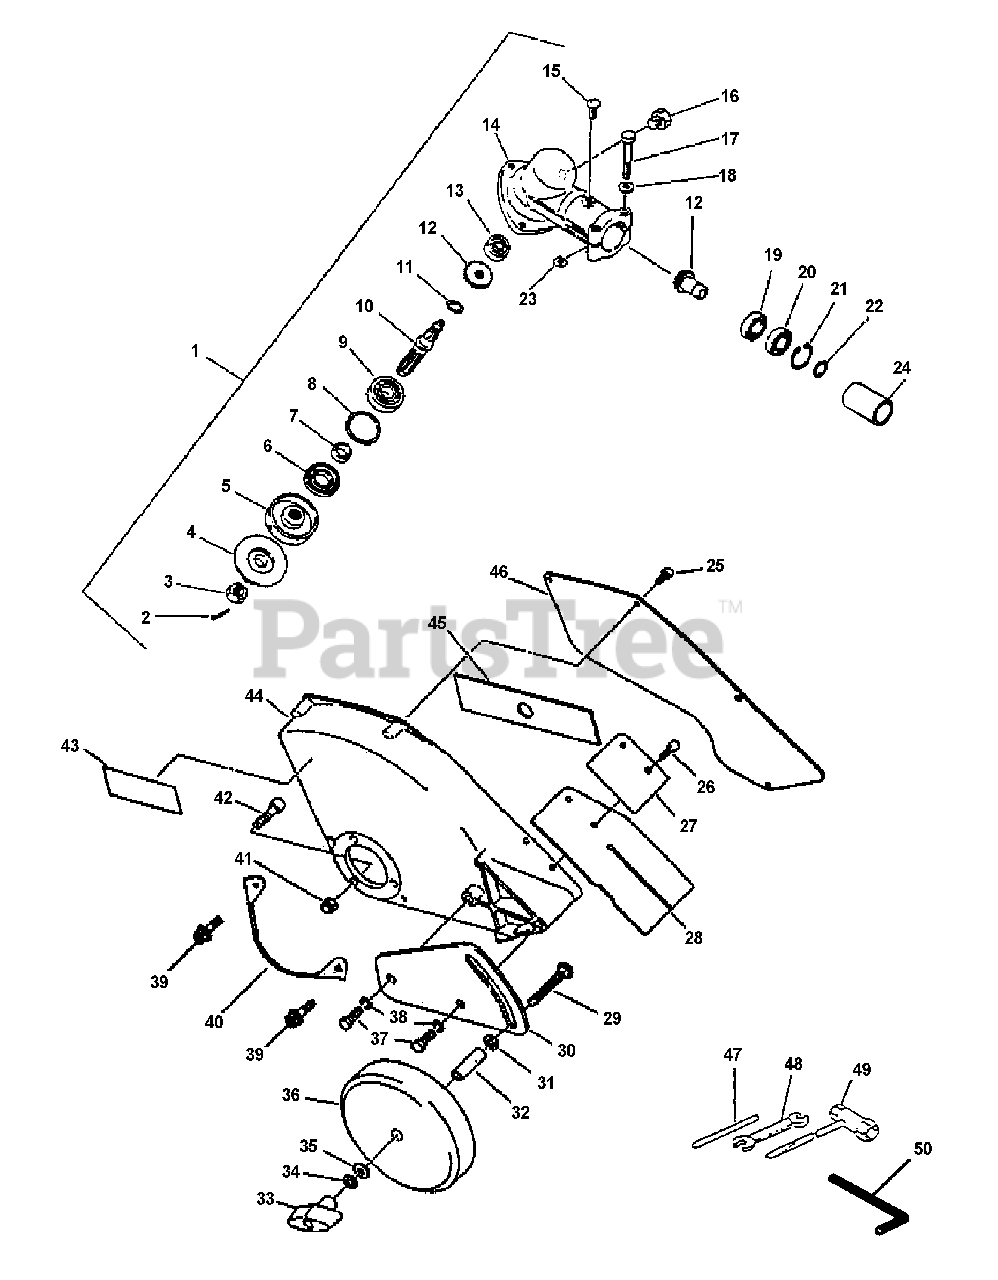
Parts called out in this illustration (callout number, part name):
1	GEAR CASE ASSY
2	PIN, COTTER 2×22
3	NUT 10×1.25 LH
4	PLATE, ADAPTOR - LOWER
5	PLATE, ADAPTER - UPPER
6	SEAL, OIL 22
7	SPACER 11.8×15×9
8	RING, SNAP Ø32
9	BEARING, BALL - 6201 C3
10	SHAFT, GEAR
11	RING, SNAP Ø12
12	GEAR SET
13	BEARING, BALL 6000
14	CASE, GEAR
15	SCREW 5×10
16	BOLT 8×8 SP
17	BOLT 5×40
18	WASHER, FLAT 5.5×10×0.8
19	BEARING, BALL 6001
20	BEARING, BALL 6001
21	RING, SNAP 28
22	RING, RETAINING - 12
25	BOLT 4×12
26	BOLT 4×14
27	PLATE, FLAP
28	FLAP, DEBRIS
29	BOLT 5/16"-18×2-1/2"
30	BRACKET, WHEEL
31	WASHER, SPRING 10
32	COLLAR 12
33	KNOB, FASTENER
34	WASHER, SPRING 8
36	WHEEL
37	BOLT 8×14
38	WASHER, SPRING 8
39	BOLT 4×12
40	GUARD, SHIELD
41	NUT, LOCK M5
42	BOLT 5×22
43	LABEL - CAUTION
44	NEW BLADE SHIELD
45	BLADE - 2 PK
46	SHIELD, DEBRIS
47	TOOL, LOCKING 5×120 MM
48	SPANNER 8×10
49	T-WRENCH 17x-19 L200
50	WRENCH, ALLEN 3 MM
